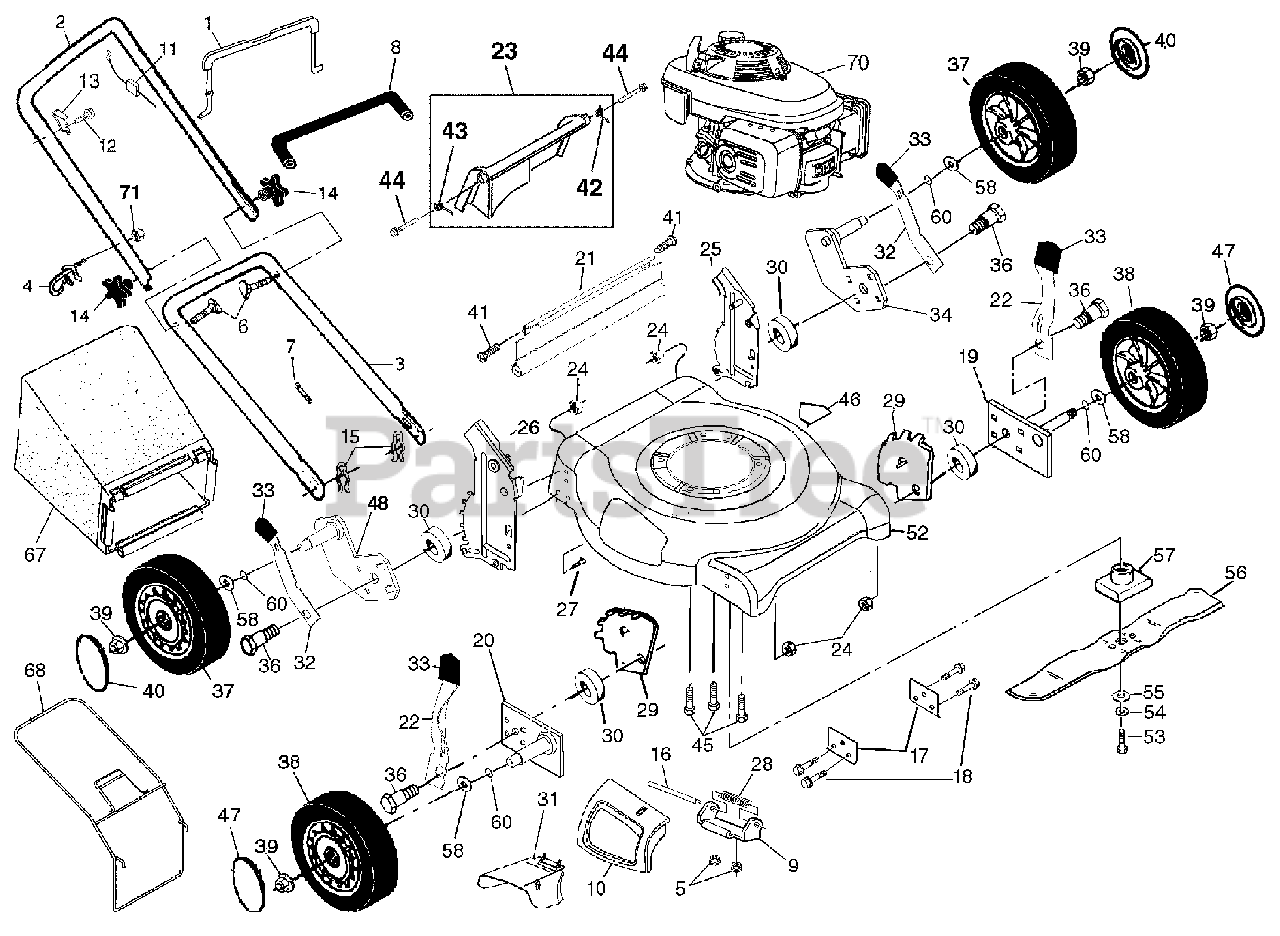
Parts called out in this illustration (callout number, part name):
1	Control Bar
2	Upper Handle, with Grip
3	Lower Handle
4	Rope Guide
5	Locknut 1/4-20
6	Handle Bolt
7	Wire Tie
8	Grip, Foam
9	Hinge Bracket
10	Mulcher Door
11	Engine Zone Control Cable
12	Hex Washer Head Screw
13	Up-Stop Bracket
14	Handle Knob
15	Hairpin Cotter
17	Support Bracket
19	Axle Arm Assembly - LF
20	Axle Arm Assembly - RF
21	Rear Skirt
22	Selector Spring - Front
23	Rear Door Assembly Kit
24	Locknut 5/16-18
25	Handle Bracket Assembly (Left)
26	Handle Bracket Assembly (Right)
27	Screw 1/4-20 x 3/8
28	Hinge Spring
29	Wheel Adjusting Bracket - Front
31	Clip on Discharge Guard
32	Selector Spring - Rear
33	Selector Knob
34	Axle Arm Assembly - LR
36	Shoulder Bolt 5/16-18
37	Wheel Assembly, Rear
38	Wheel Assembly, Front
39	Flanged Locknut
41	Hinge Screw
42	Spring (LH)
43	Spring (RH)
45	Hex Head Thread Rolling Screw 3/8-16 x 1
46	Danger Decal
47	Hubcap
48	Axle Arm Assembly - RR
52	Housing Assembly
53	Hex Head Screw 3/8-24 x 1-3/8 Grade 8
54	Helical Lockwasher
55	Hardened Washer
56	21" Blade
57	Blade Adapter
58	Washer, Flat 3/8
60	O-Ring
67	Grass Catcher
68	Frame, Grass Catcher
